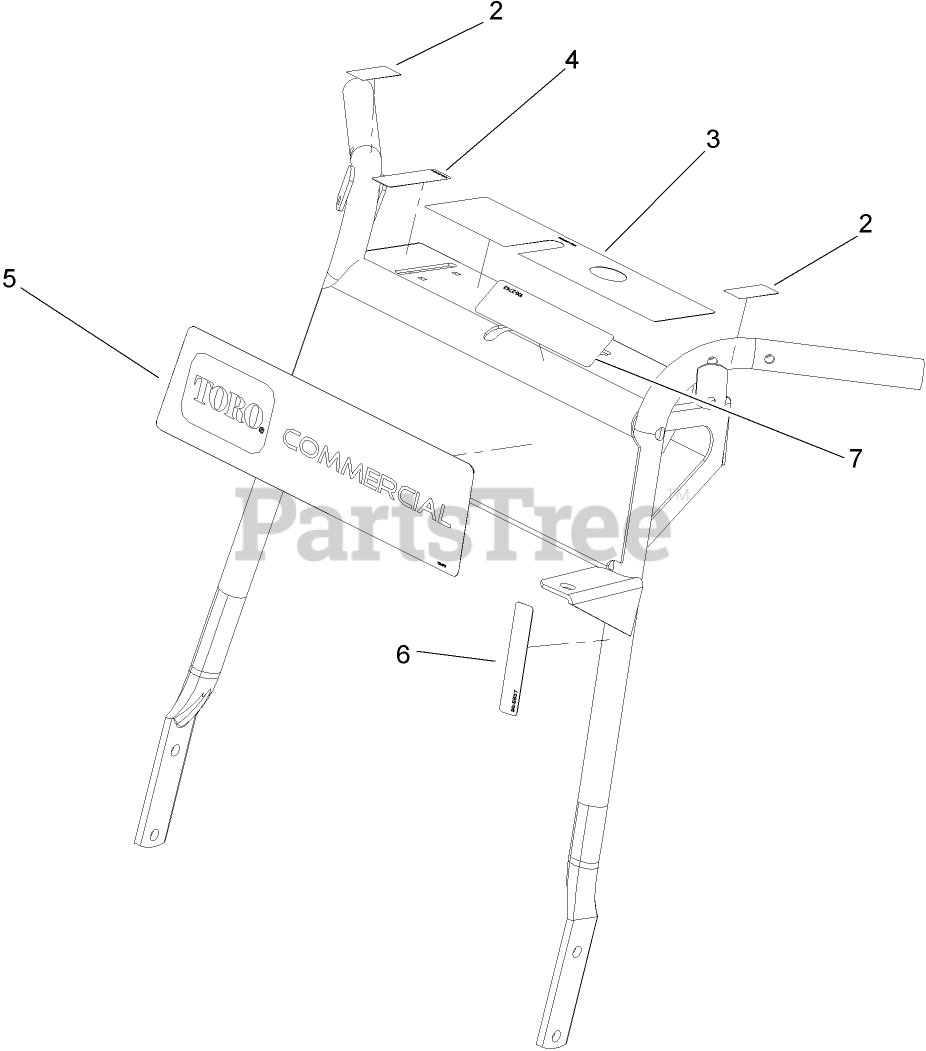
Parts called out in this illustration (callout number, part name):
2	DECAL-LOCK, NEUTRAL
3	DECAL-WARNING
4	DECAL-THROTTLE
6	DECAL-ENGAGE, DECK
7	DECAL-CAUTION, BRAKE
